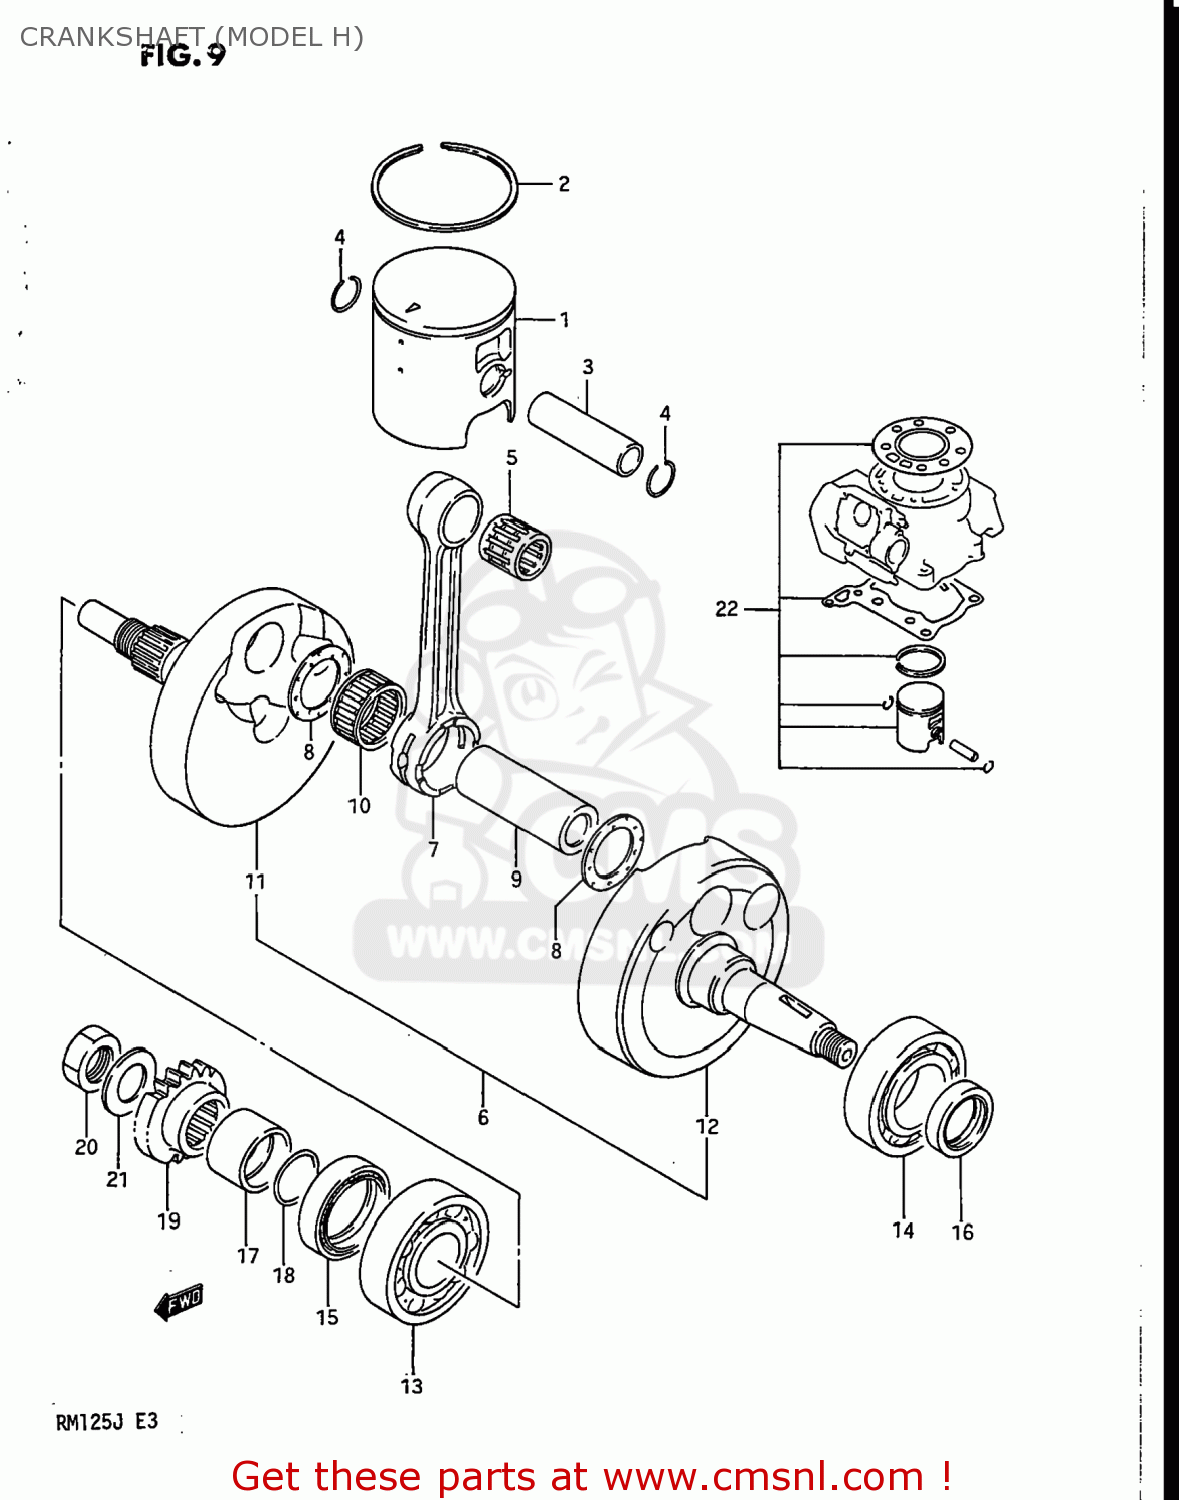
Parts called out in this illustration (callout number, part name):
1	PISTON
2	RING,PISTON
3	PIN,PISTON
4	RING,SNAP 14MM
5	BEARING(14X18X20)
6	CRANKSHAFT ASSEMBLY
7	CONNECTING ROD
8	WASHER(22X35X1)
9	PIN,CRANK
10	BEARING
11	CRANKSHAFT,RIGHT
12	CRANKSHAFT,LEFT
13	BEARING
14	BEARING(25X52X15)
15	SEAL,OIL(28X40X8)
16	OIL SEAL
17	SPACER,PRIMARY DRIVE GEAR
18	O RING(D:2.4,ID:19.8)
19	GEAR,PRIMARY DRIVE
20	NUT
21	WASHER
22	PISTON KIT (STD)
